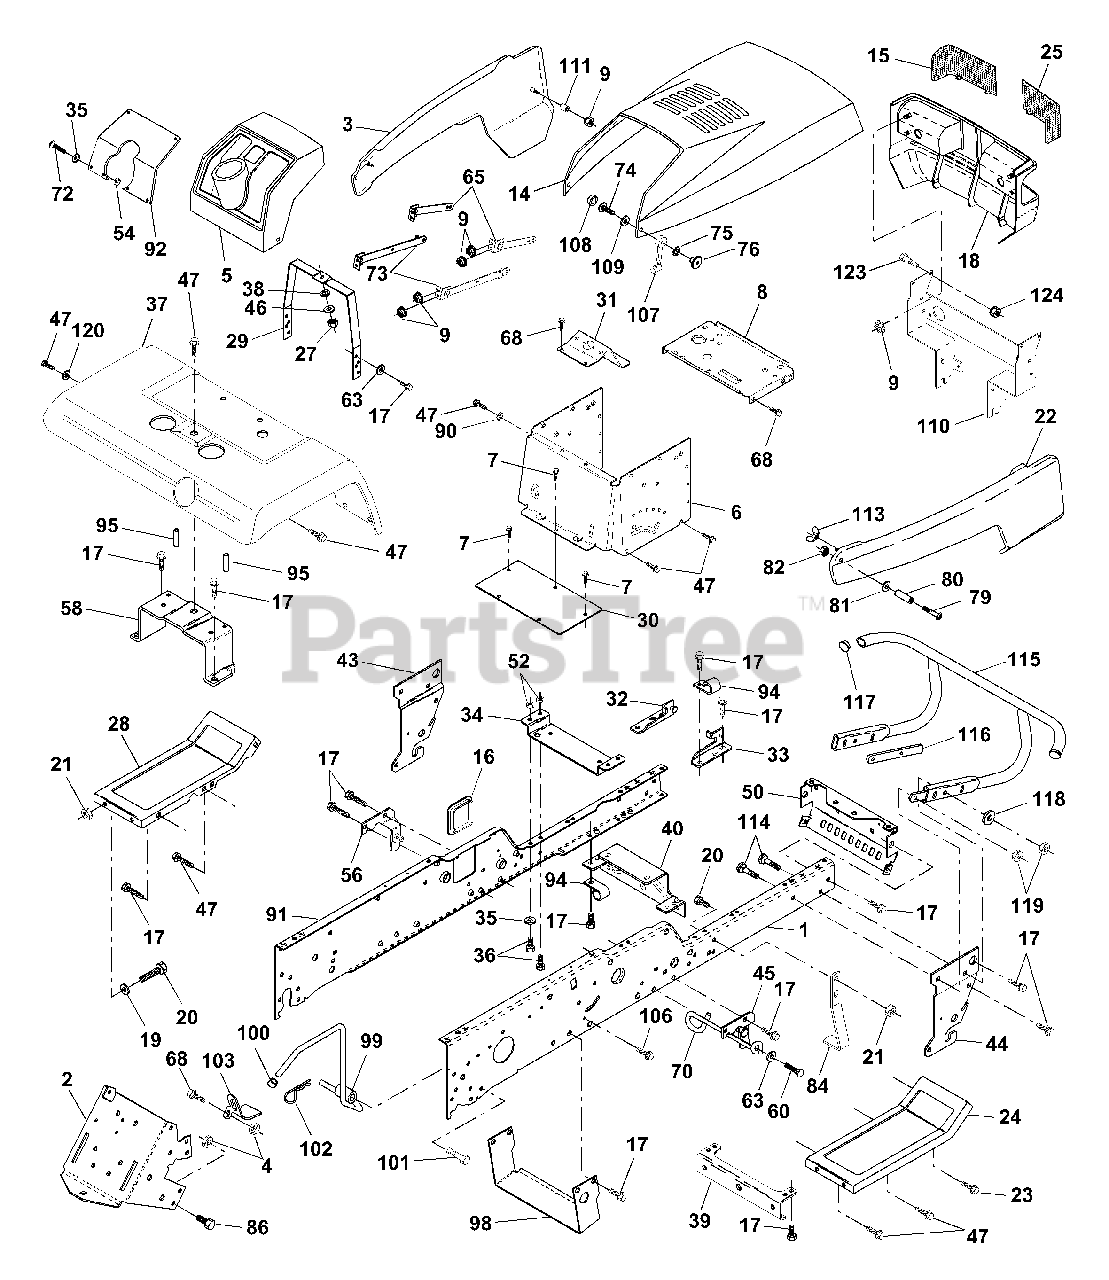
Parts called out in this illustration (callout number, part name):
1	Rail, Frame RH
2	Drawbar, Gt
3	Panel Asm., Side LH
4	Nut, Lock Hex 7/16 Unc
5	Dash, Plastic Black
6	Dash Asm., Lower
7	Screw, Thd Cut 1/4-20 x 1/2
8	Support, Battery
14	Hood Asm., Pnt
15	Lens Headlight LH
16	Cover, Access
17	Screw, Thdrol 3/8-16 x 3/4
18	Grille
19	Washer 13/32 x 13/16 x 12 Ga.
20	Bolt, Fin Hex 3/8-16 x 1
21	Nut, Crownlock 3/8-16
22	Panel Asm., Side RH
24	Footrest, RH
25	Lens, Headlight RH
27	Nut, Fin Hex 1/4-20
28	Footrest, LH
29	Bracket, Support Dash
31	Brace, Support Steering
32	Bracket Asm., Frame Pivot Lh
33	Bracket Asm., Frame Pivot Rh
34	Bracket, Engine Support Rear
35	Washer 11/32 x 11/16 x 16 Ga.
36	Bolt, Fin Hex 5/16-18 x 3/4
37	Fender, Pnt.
38	Washer, Lock 1/4
39	Bracket, Axle Front
40	Bracket, Support Axle/Engine
43	Bracket, Spnsn Front Lh
44	Bracket, Spnsn Front Rh
45	Bracket Asm., Susp Chassis Rh
46	Washer 9/32 x 3/4 x 16 Ga.
47	Screw Thdrol 3/8-16 x 1/2
50	Bracket, Chassis Front
52	Nut, Crownlock 5/16-18
54	Nut 5/16-18
56	Bracket Asm., Susp Chassis Lh
58	Bracket Asm., Fender
60	Screw Thdrol 3/8-16 x 1-1/4
63	Washer 13/32 x 1 x 14 Ga.
65	Strap, Asm. Hinge Front
68	Screw Thdrol. 5/16-18 x 1/2
70	Guide, Belt Mid Span
72	Screw, Mach Trhd 5/16-18 x 3/4
73	Strap, Asm. Hinge Rear
74	Screw, Machine #10-24
75	Washer, Lock #10
76	Nut, Weld #10-24
79	Screw, Machine #10-24 x 1/4
80	Spacer, Split
81	Washer 7/32 x 1/2 x 18 Ga.
82	Nut #10-24
84	Stop, Over Center Mower
86	Bolt, Fin Hex 7/16-14 Unc x 1
90	Washer, Lock External Tooth 3/8
91	Rail, Frame Lh
92	Plate, Silkscreen Dash
94	Clip, Fuel Line
95	Push Nut, Nylon
98	Bracket Chassis Skid
99	Rod Asm. Bypass
100	Cap Brake Parking Black
101	Screw Thdrol. 3/8-16 x 1-3/4
102	Retainer Spring
103	Bracket Lock Bypass
106	Screw Thdrol Hex Head Zinc MWR
107	Latch, Chute Blk
108	Cap, Snap Black
109	Cap, Washer Snap
110	Support Asm. Grille
113	Nut, Plastic Locking Wing 1/4-20
114	Bolt, Carriage 3/8-16 x 1-1/4
115	Bumper Asm. W/Poly Bag
116	Bracket, Extension Bumper
117	Plug Plastic
118	Washer 13/32 x 13/16 x 16 Ga.
119	Nut, Crownlock 3/8-16 UNC
120	Washer 13/32 x 1 x 16 Ga.
123	Bolt, Shoulder 1/4-20
124	Nut Crownlock 1/4-20
